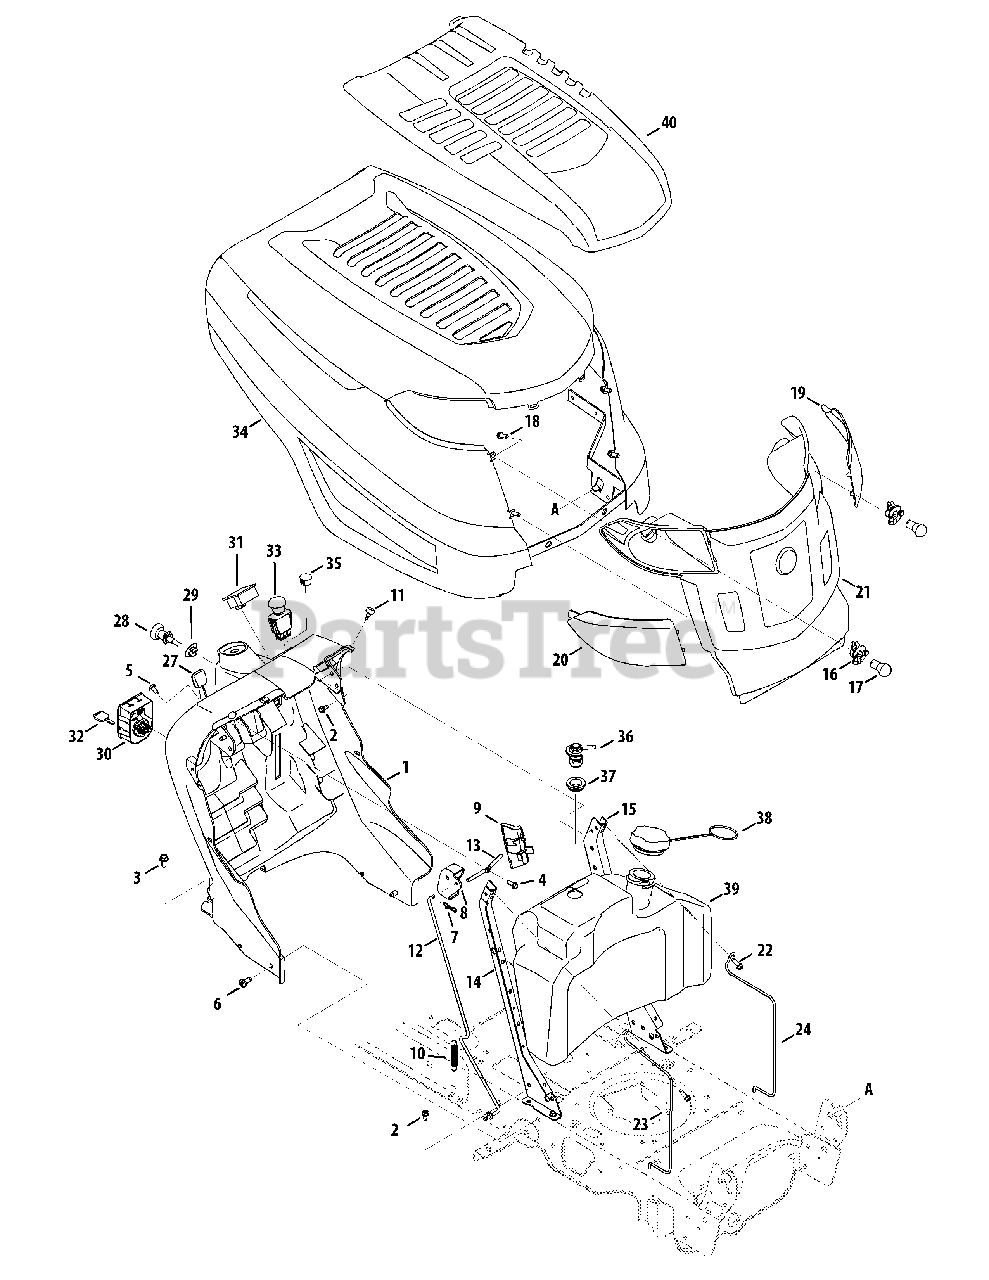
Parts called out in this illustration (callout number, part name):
1	Dash Panel (Manual PTO)
1	Dash Panel (Elect PTO)
2	Screw, 1/4-20 x .50
3	Hex Wash HD S-Tapp Scr 5/16-18 x .75
4	Hex Tapp Scr 1/4 x .75" Lg.
5	Torx Mach. AB-Tapp Scr. 1/4-14 x .625 Lg
6	Screw 5/16-18 x .75
7	Bow Tie Cotter Pin
8	Dash Lever
9	Cruise Cover
10	Extension Spring .500 Dia. x 2.733" Lg.
11	Bumper
12	Control Rod
13	Pivot Rod
14	RH Dash Support Plate
15	LH Dash Support Plate
16	Lamp Socket
18	Screw 1/4 x .75
19	Lens LH
20	Lens RH
21	Grille Style "K"
22	TT Scr. 1/4-20 x .625 Lg.
23	LH Support Rod
24	RH Support Rod
25	Hex Screw 1/4-15 x .50
27	Throttle/Choke Cont. Cable (Single Cyl.)
27	Throttle/Choke Cont. Cable (Kohler Twin)(w/Electric PTO)
29	Choke Plug (Single Cyl.)
30	Module Ignition Switch
31	Systems Ind. Monitor w/Hr. Meter
33	Electric PTO Switch (Electic PTO Only)
34	Hood Style "K"
36	Rollover Valve
37	Rubber Grommet
38	Cap-Fuel (w/hoop)
39	Tank Ass’y
40	Hood Scoop
